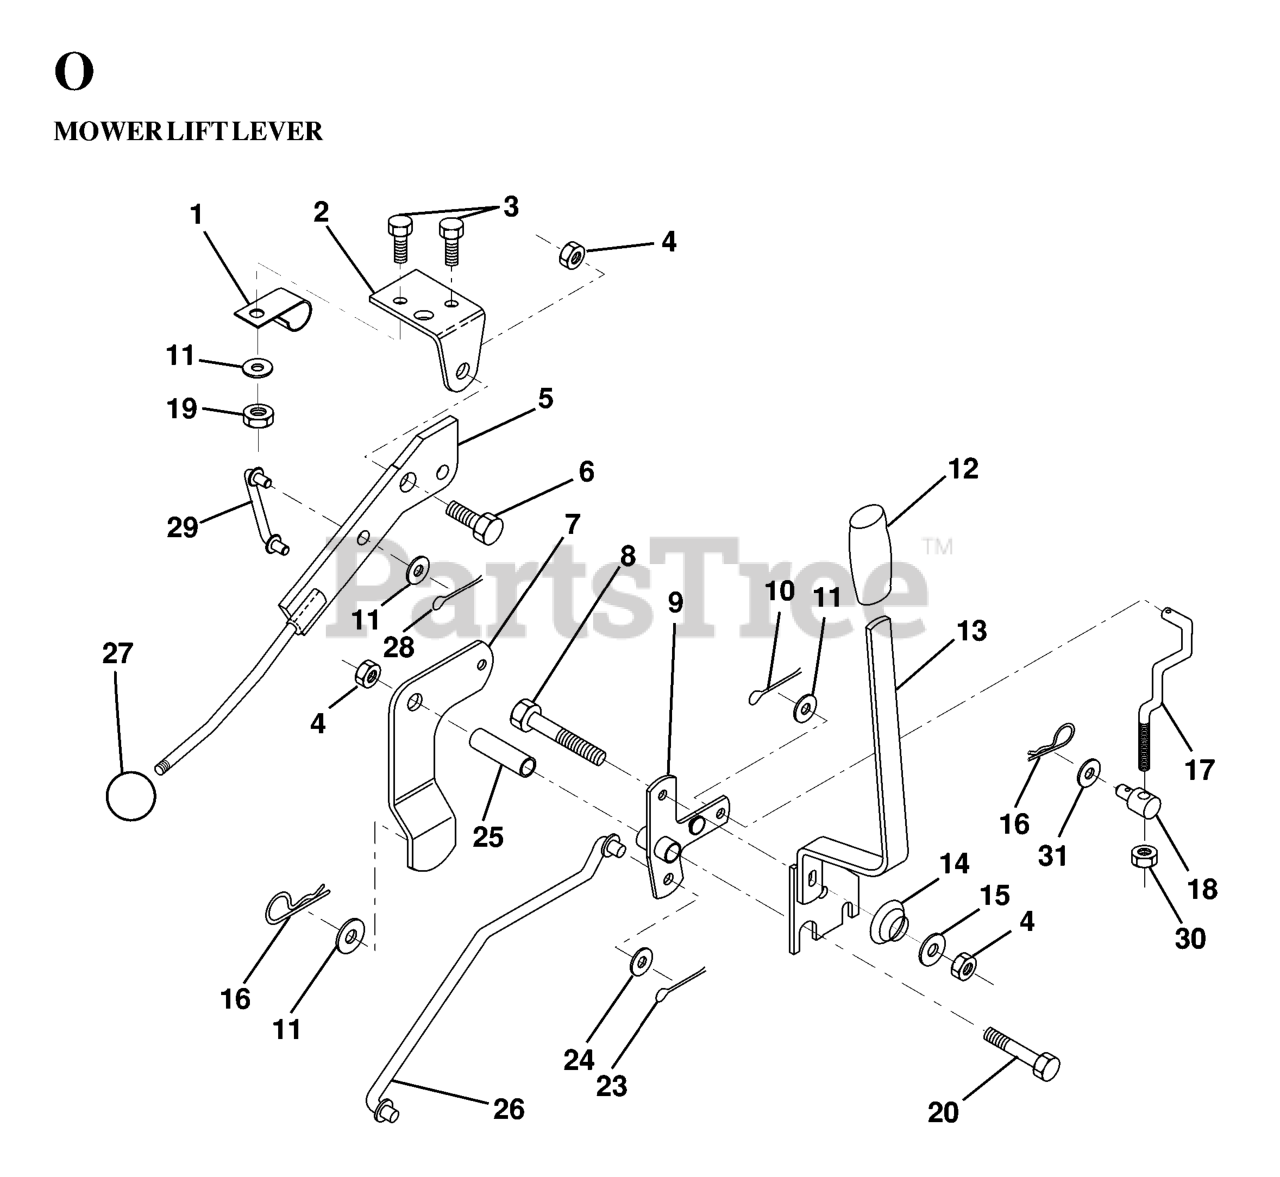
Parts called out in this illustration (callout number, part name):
1	CLIP,INSULATOR
2	BRKT CLUTCH
3	BOLT
5	CLUTCH LEVER
6	BOLT, SHOULDER LT
7	ASSEMBLY MOWER CLUTCH ARM
9	BELLCRANK,LIFT
10	COTTER PIN
11	WASHER
12	GRIP HANDLE
13	LIFT HANDLE ASSY
14	SPRING COMPRESSIO
15	WASHER T
16	SPRING TI
17	LINK LIFT FRT
18	TRUNNION.ADJUSTABLE.3/8-16
19	NUT.CROWNLOCK.1/4
23	PIN COTTER
24	WASHER GT
25	TUBE SPACER
28	COTTER PIN
29	LINK MOWER CLUTCH
30	NUT
31	WASHER
